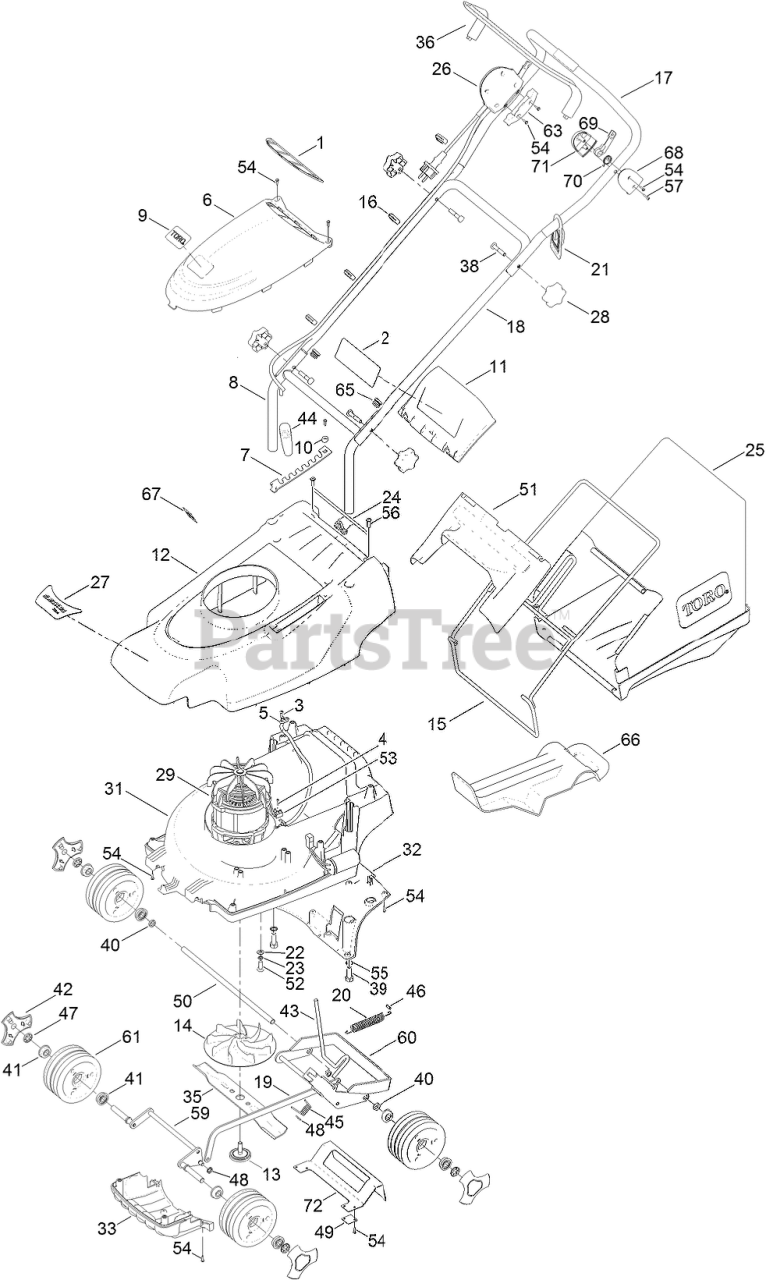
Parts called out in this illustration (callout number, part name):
1	VENT MESH ASM
2	DECAL-SAFETY, ELECTRIC
5	CLAMP-CABLE
6	COVER-MOTOR
7	PLATE-HOC
8	HANDLEBAR-LOWER
9	DECAL-TORO
10	COVER-SCREW, HOC
11	DEFLECTOR-REAR
12	COVER-TOP
13	BOLT-FIXING, CUTTERBAR (NYLON)
14	CARRIER-CUTTERBAR
15	FRAME-GRASSBAG
16	CLIP-CABLE
17	HANDLEBAR-UPPER
18	HANDLEBAR-MIDDLE
19	ROD-CONNECTING
20	SPRING-BALANCE, COUNTER
21	CLEAT-CABLE
22	WASHER
23	WASHER-SPRING
24	ROD-DEFLECTOR
25	GRASSBAG
26	SWITCH AND LEAD ASM
28	KNOB-HANDLEBAR
29	MOTOR
31	UNDERDECK
32	THROWPLATE
35	CUTTERBAR
36	ARM-BAIL
38	BOLT-HANDLEBAR
39	BOLT-PLASTIC
40	SPACER-WHEEL, REAR
41	BEARING-WHEEL
42	CAP-HUB
43	LEVER-HOC
44	KNOB-HOC
45	SPRING-HOC
46	PIN-SPRING, HOC
47	WASHER-STARLOCK
48	WASHER-STARLOCK
49	PLATE-PIVOT, AXLE
50	ROD-AXLE, REAR
51	TOP-GRASSBAG
52	BOLT-MOTOR
53	BLOCK-TERMINAL
55	WASHER
56	SCREW
57	SCREW-PPH
59	FRONT AXLE ASM
60	REAR AXLE ASM
61	WHEEL ASM
63	SWITCH-LEFT, LOWER
65	PLUG-TUBE
66	PLUG-MULCHING
67	DECAL-HOC
68	MOUNT-LEFT
69	LEVER-MOUNT
70	SPRING-BAILARM
71	MOUNT-RIGHT
72	GUARD-PLATE, AXLE
